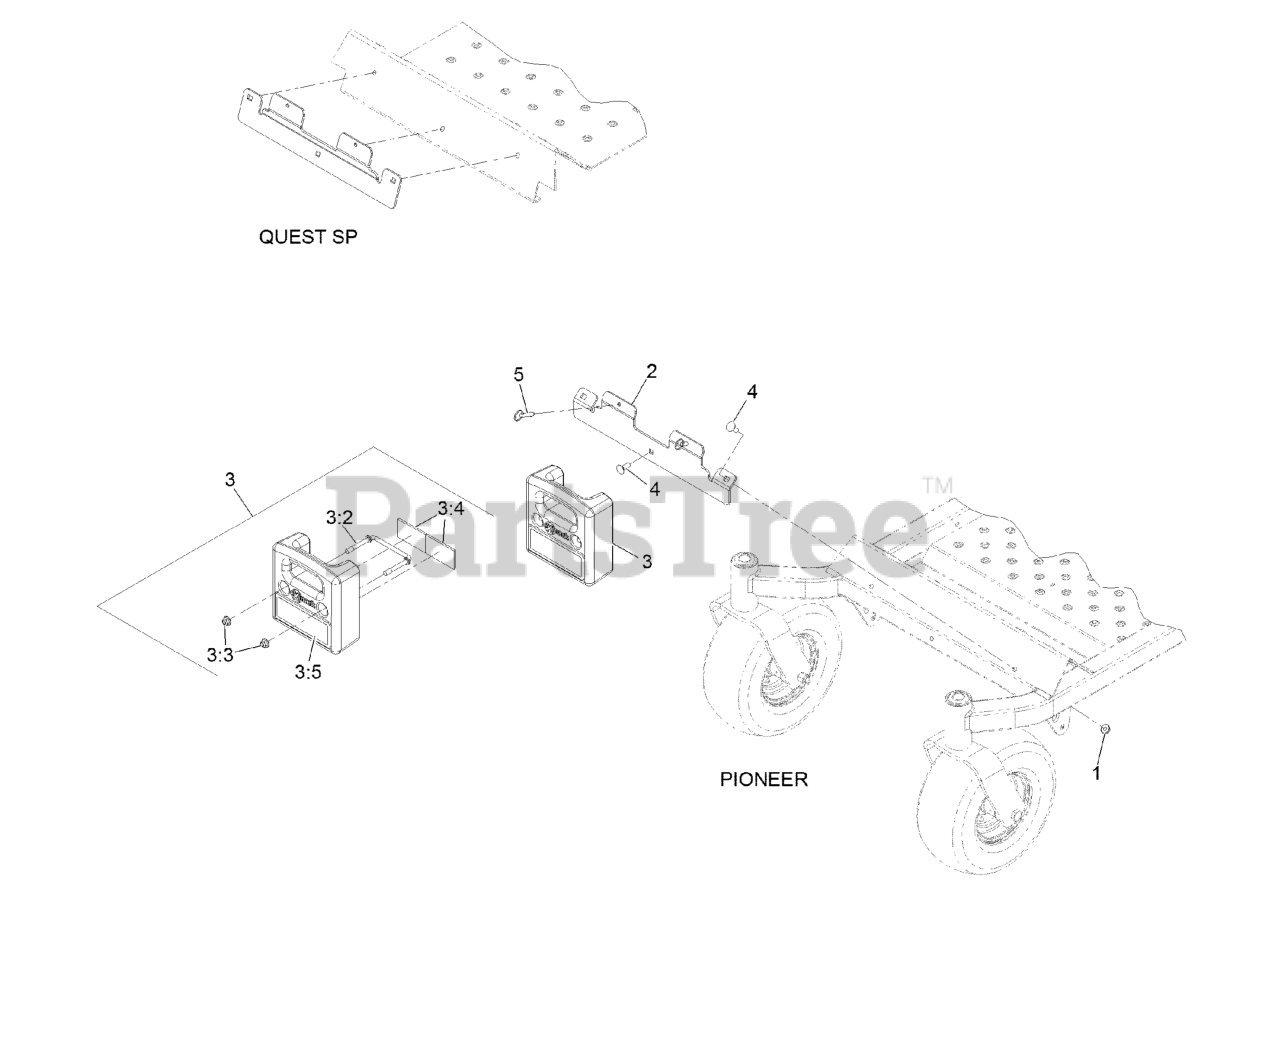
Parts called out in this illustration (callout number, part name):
1	NUT-HF, NI
2	BRACKET-WEIGHT MOUNT
3	WEIGHT ASM
3:2	WIREFORM-WEIGHT
3:3	NUT-HF, NI
3:4	CUSHION-RUBBER
3:5	DECAL-WARNING WEIGHT
4	BOLT-CARR
5	PIN-BALL, DETENT
